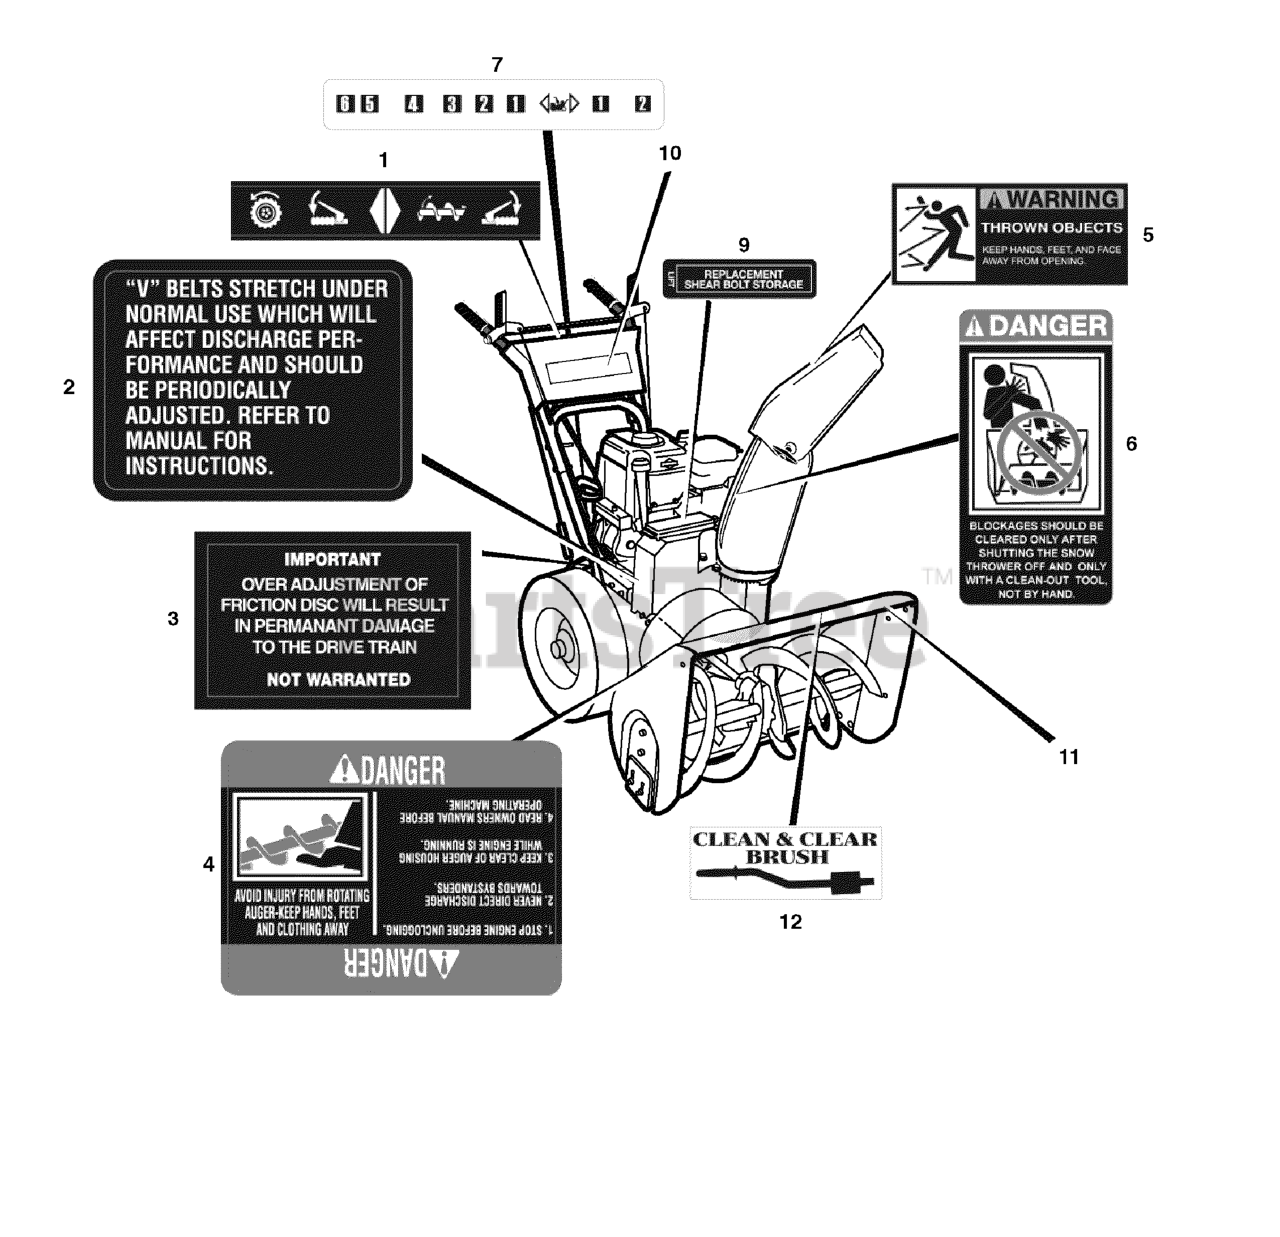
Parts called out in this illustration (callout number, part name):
1	DECAL, Hand Control
2	DECAL, V-Belts
3	DECAL, Over Adjustment
4	DECAL, Rotating Auger
5	DECAL, Thrown Objects
6	DECAL, Danger, Unclogging Chute, Hand
7	DECAL, Speed Control
9	DECAL, Shear Bolts
10	DECAL, Plate, John Deere
11	DECAL, 726E
12	DECAL, Clean & Clear Brush
14	DECAL, Leaping Deer Logo
15	MANUAL, Operator's
16	MANUAL, Parts List
